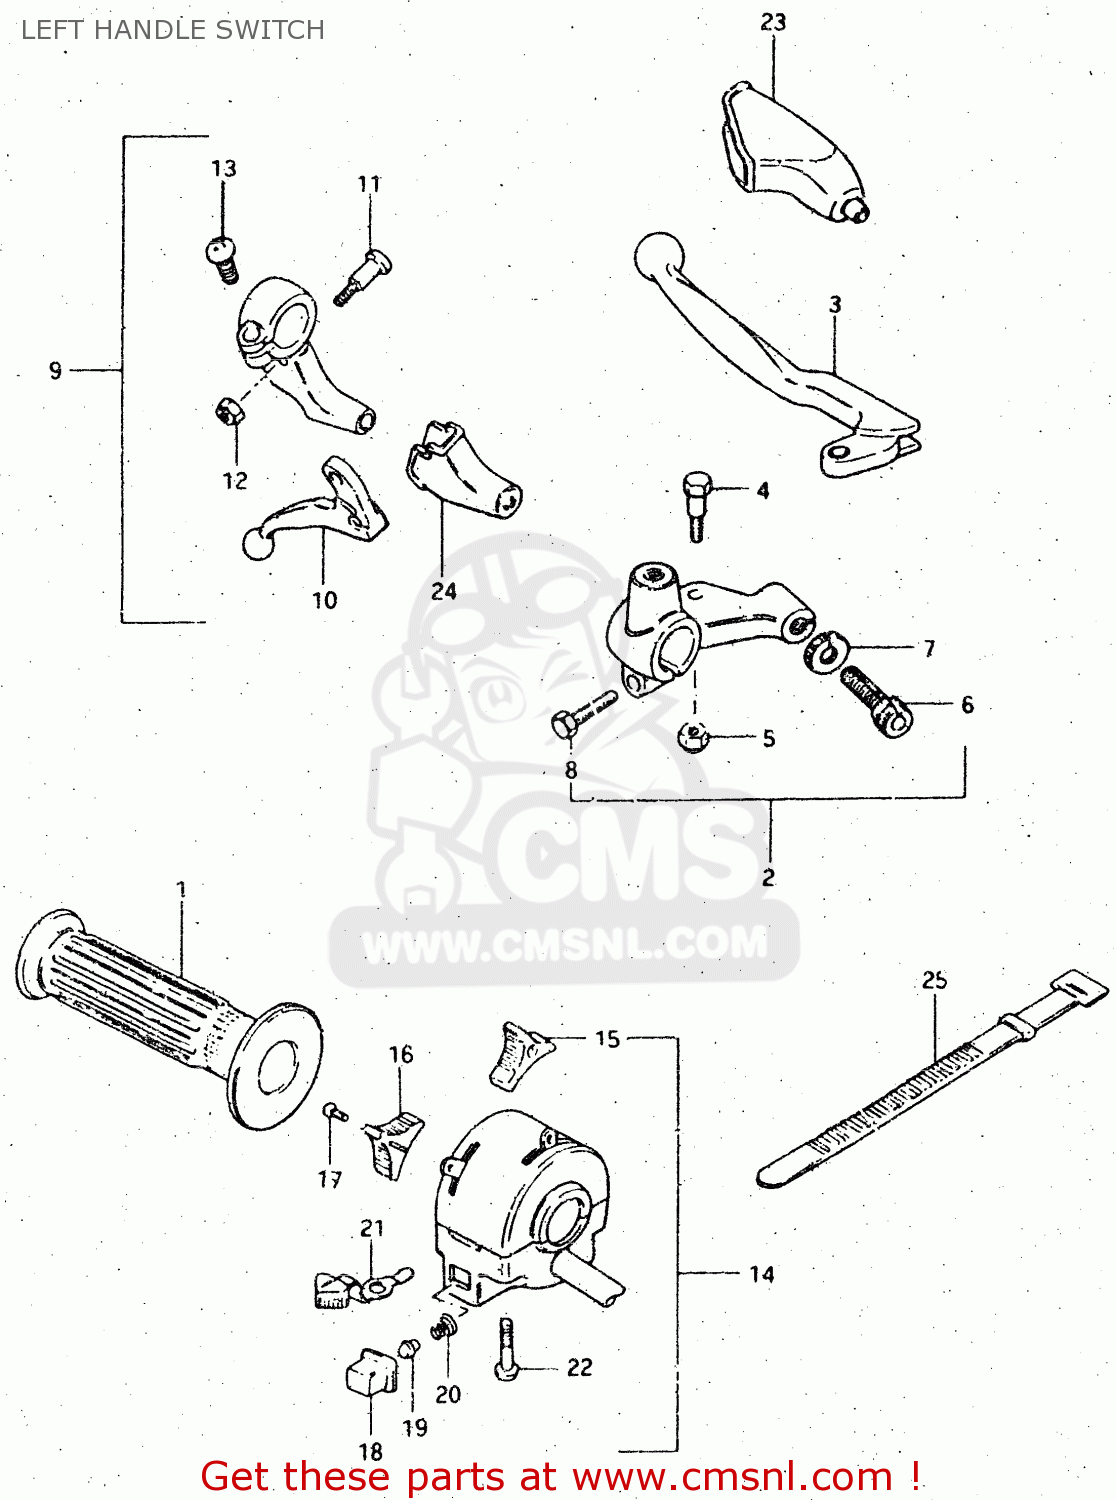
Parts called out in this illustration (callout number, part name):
1	GRIP,L
2	LEVER ASSY,CLUTCH
3	LEVER,CLUTCH
4	BOLT,LEVER
5	NUT 6MM
6	ADJUSTER,CABLE
7	NUT,CABLE ADJUSTER
8	BOLT,CLUTCH LEVER HOLDER
9	LEVER ASSEMBLY,DECOMPRESSION
10	LEVER,DECOMP
11	BOLT,LEVER
12	NUT
13	SCREW
14	SWITCH ASSY, HANDLE LH
15	KNOB,LIGHTING SWITCH
16	KNOB, DIMMER
17	SCREW
18	BUTTON,HORN
19	CONTACT
20	SPRING
21	KNOB,TURNSIGNAL
22	SCREW
23	COVER,CLUTCH LEVER
24	COVER,DECOMP LEVER DUST
25	CLAMP
